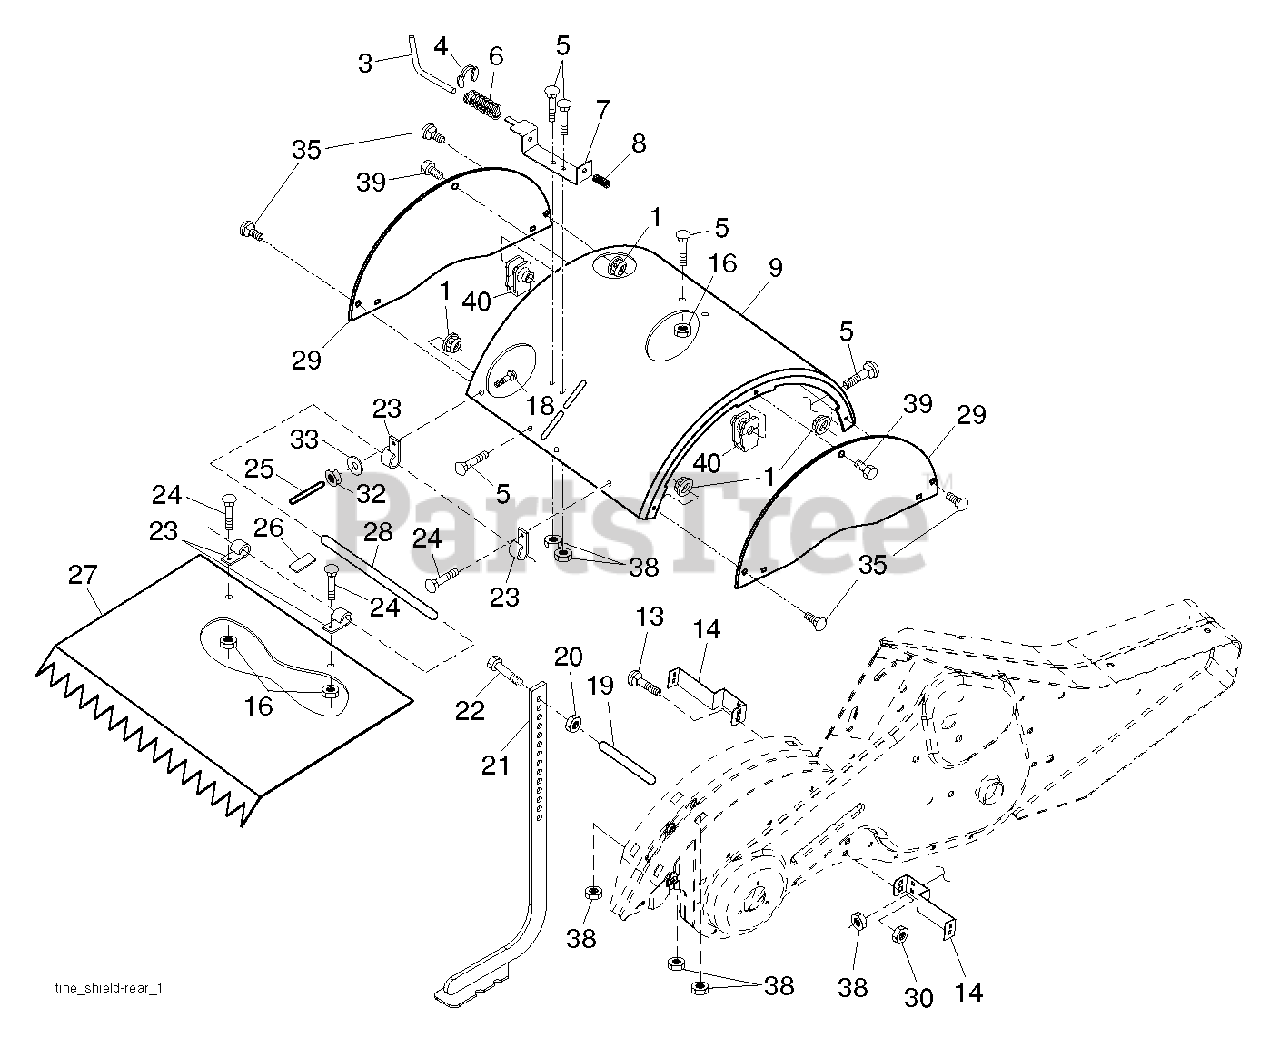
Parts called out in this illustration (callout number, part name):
1	NUT.FLANGE.5/16
3	STAKE PIN TI
4	RING, KLIP
5	BOLT, RDHD SQNK 5/16-18 X 3/4
6	SPRING TI
7	Latch Stake Bracket, 3 20 Black
8	SPRING CRT
13	BOLT.CARRIAGE.5/16-18
16	NUT T
20	NUT.HEX.3/8-16UNC
22	BOLT.375-16
23	HINGE CRT
25	VINYL CAP TI
26	PAD IDLER TI
28	PIN.HINGE.TILLER
29	RP.SHIELD.ASM.PNT.SIDE.RED
30	LOCKNUT-FLANGE 5/16-18
32	NUT
33	LOCKWASHER
35	BOLT
38	NUT
39	BOLT.HEX.HD.WASHER.5/16-18X.75
40	NUT, SPEED 5/16-18
